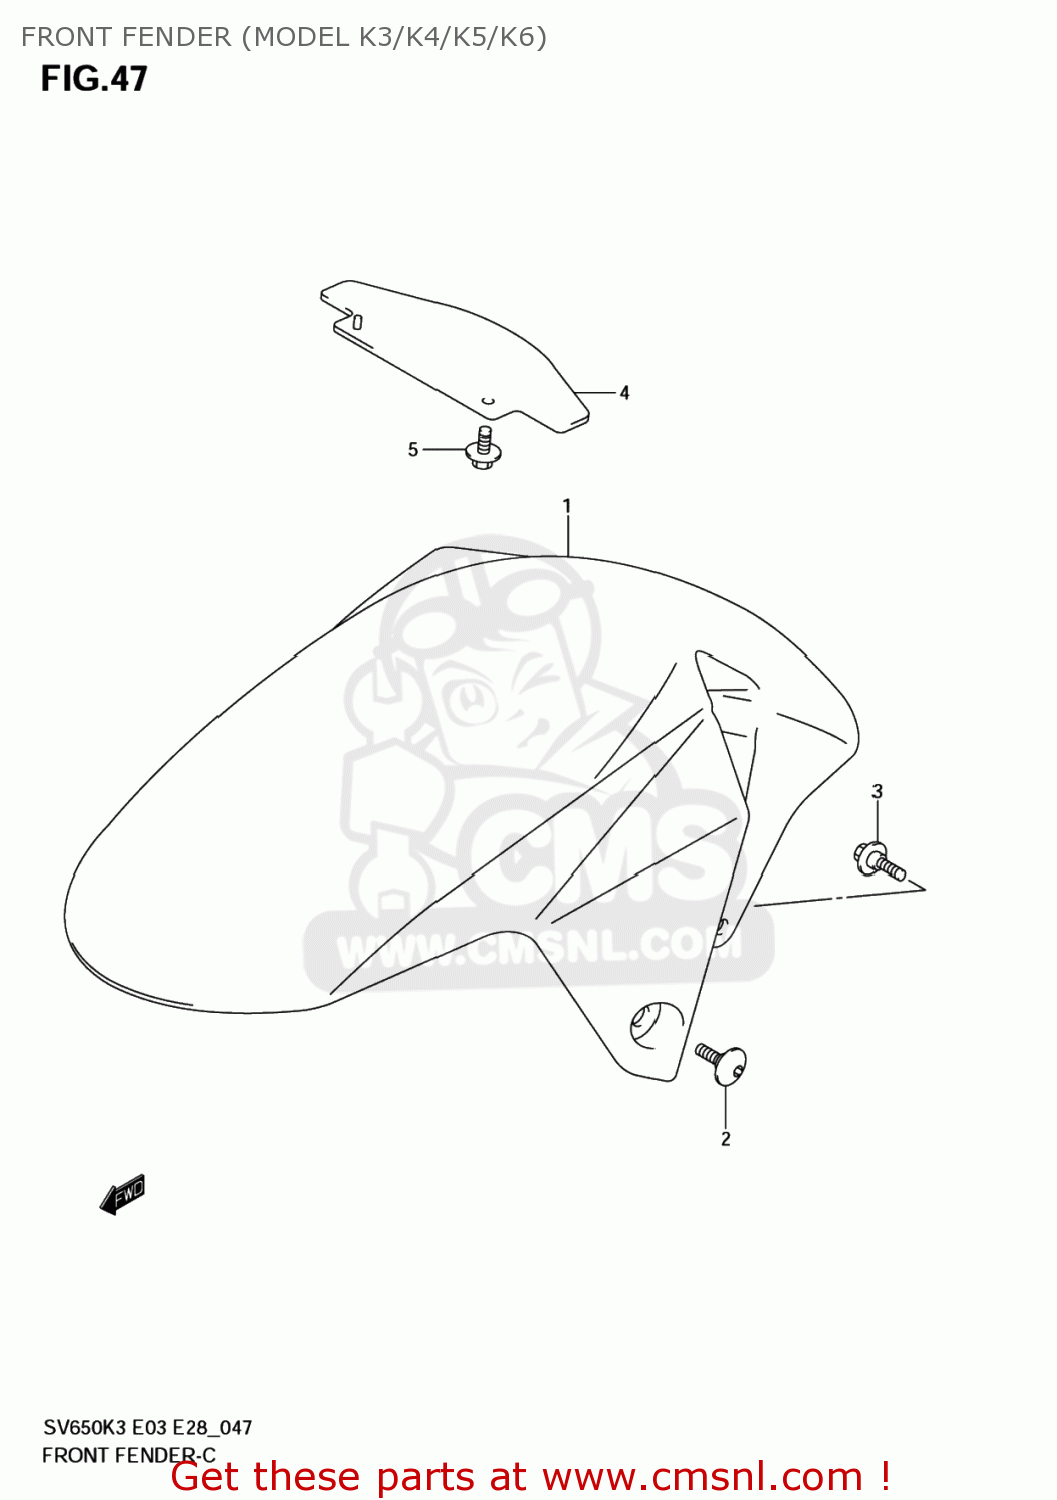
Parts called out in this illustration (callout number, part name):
1	FENDER,FRONT
2	SCREW(6X16)
3	SCREW(6X16)
4	FENDER,FR UPPER
5	BOLT(6X12)
